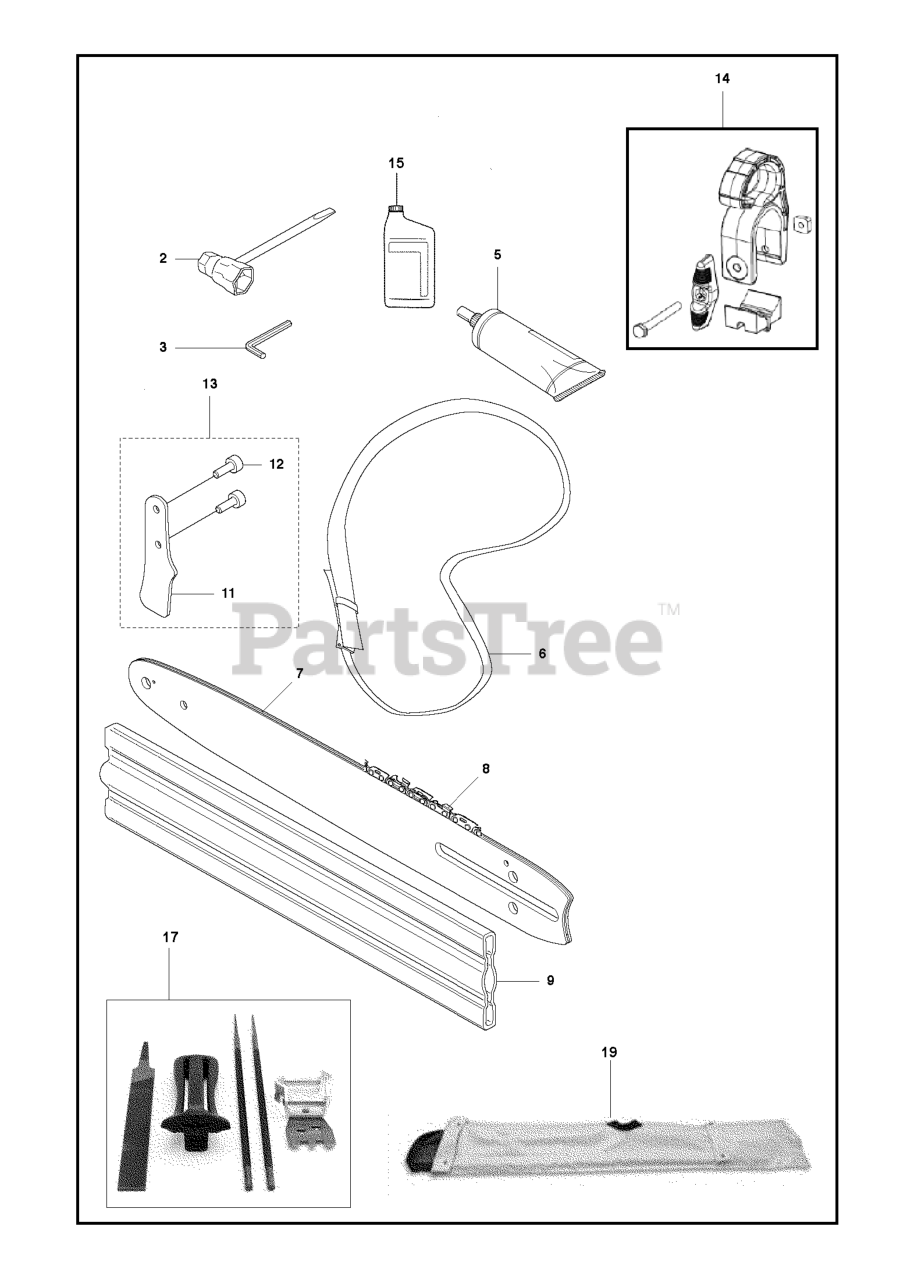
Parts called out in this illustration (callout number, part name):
2	COMBI TOOL
6	HARNESS WITHOUT HOOK
7	HUS 12" BAR LAM 3/8MIN 050 44D
8	12" CHN S93G 3/8 MIN .050 44DL
11	SHEET HOOK
12	SCREW ITXSCM
14	HARNESS BRACKET ASSY
15	BAR CHAIN OILS
17	HUS FILE KIT 3/8 MINI (S93G)
